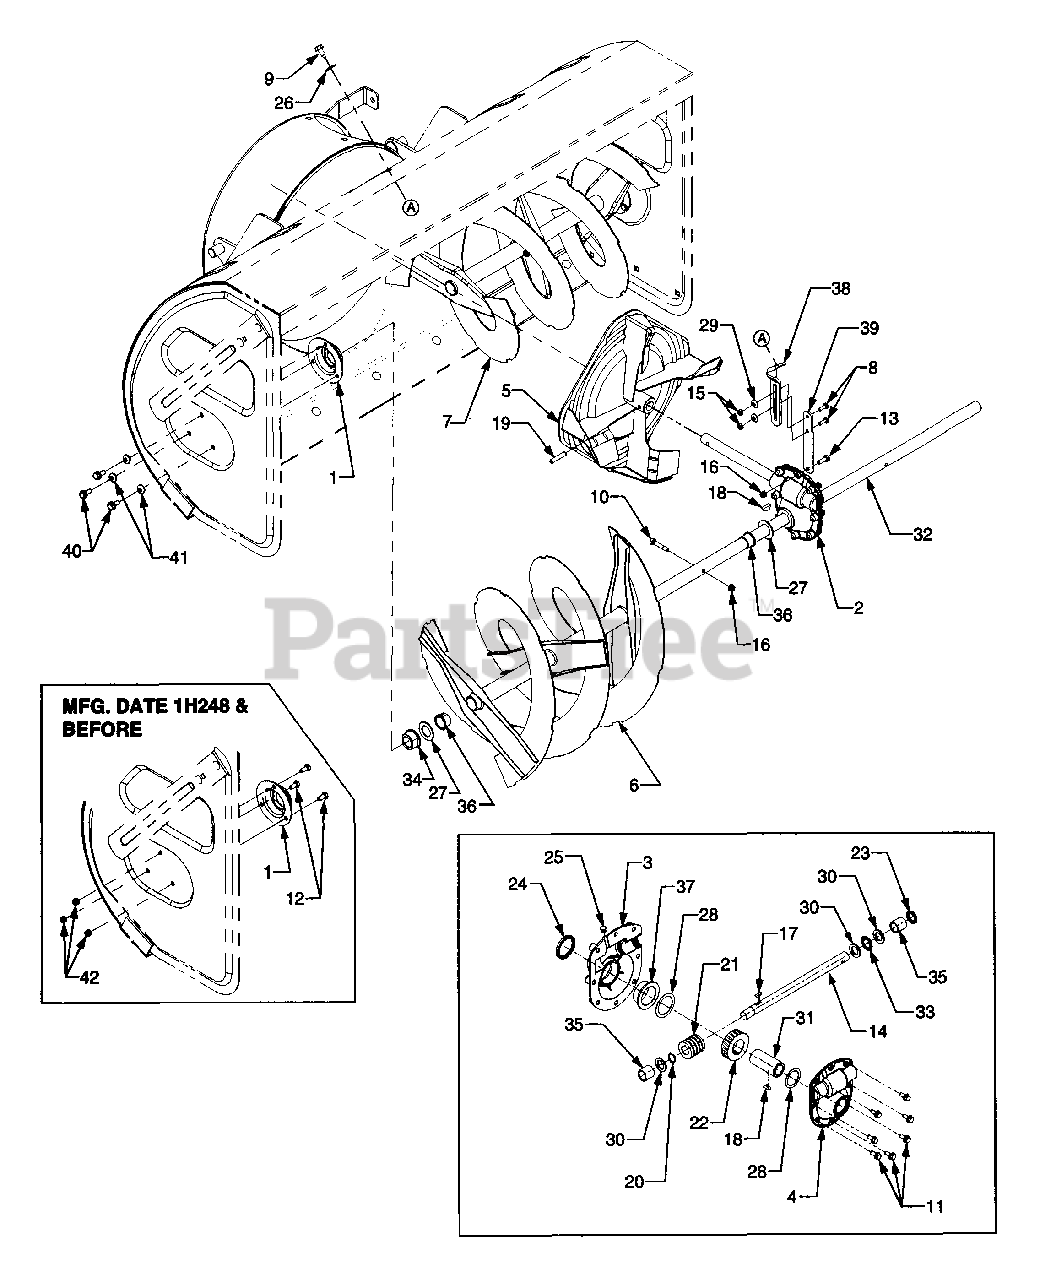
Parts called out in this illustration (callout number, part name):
1	Housing, Bearing
2	Auger Gear Box Assembly
3	Housing, Gear - RH
4	Housing, Gear - LH
5	Impellar Assembly
6	Spiral Assembly - RH
7	Spiral Assembly - LH
8	Screw, Hex Cap, 1/4-28 x .75 GR5
9	Screw, Hex Wash. Hd. Tapp 5/16-12 x .75
10	Bolt, Shear, 5/16-18 x 1.75
11	Screw, Hex Wash. Hd. Tapp 5/16-18 x .75
12	Screw, Hex Cap, 5/16-18 x .625 GR5
13	Screw, Hex Cap, 5/16-18 x .875 GR5
14	Shaft, Input
15	Nut, Hex, 1/4-28 GR5
16	Nut, Hex Insert Lock, 5/16-18
17	Key, Hi Pro, 3/16 x 3/4
18	Key, Woodruff, 1/4 x 3/4
19	Pin, Spirol, 5/16 x 1.75
20	Ring, Snap, .875 Shaft
21	Gear, Worm
22	Gear, Worm
23	Seal, Oil
24	Seal, Oil
25	Plug, 1/4 x .437
26	Washer, Bell, .340 x .872 x .06
27	Washer, Flat, 1.0 x 1.75 x .1
28	Washer, Flat, 1.5 x 2.0 x .3
29	Washer, Bell, .265 x .75 x .062
30	Washer, Flat, .88 x 1.4 x .125
31	Shaft, Worm Gear
32	Shaft, Spiral Axle
33	Bearing, Thrust
34	Bearing, Flange w/Flats
35	Bearing, Sleeve
36	Bushing, Flange
37	Bearing, Flange
38	Bracket, Gear Housing Support
39	Plate, Gear Housing Support
40	Screw, Hex Tap, 5/16-18 x .625
41	Washer, Belleville, 5/16
42	Nut, Hex Insert Lock, 5/16-18
